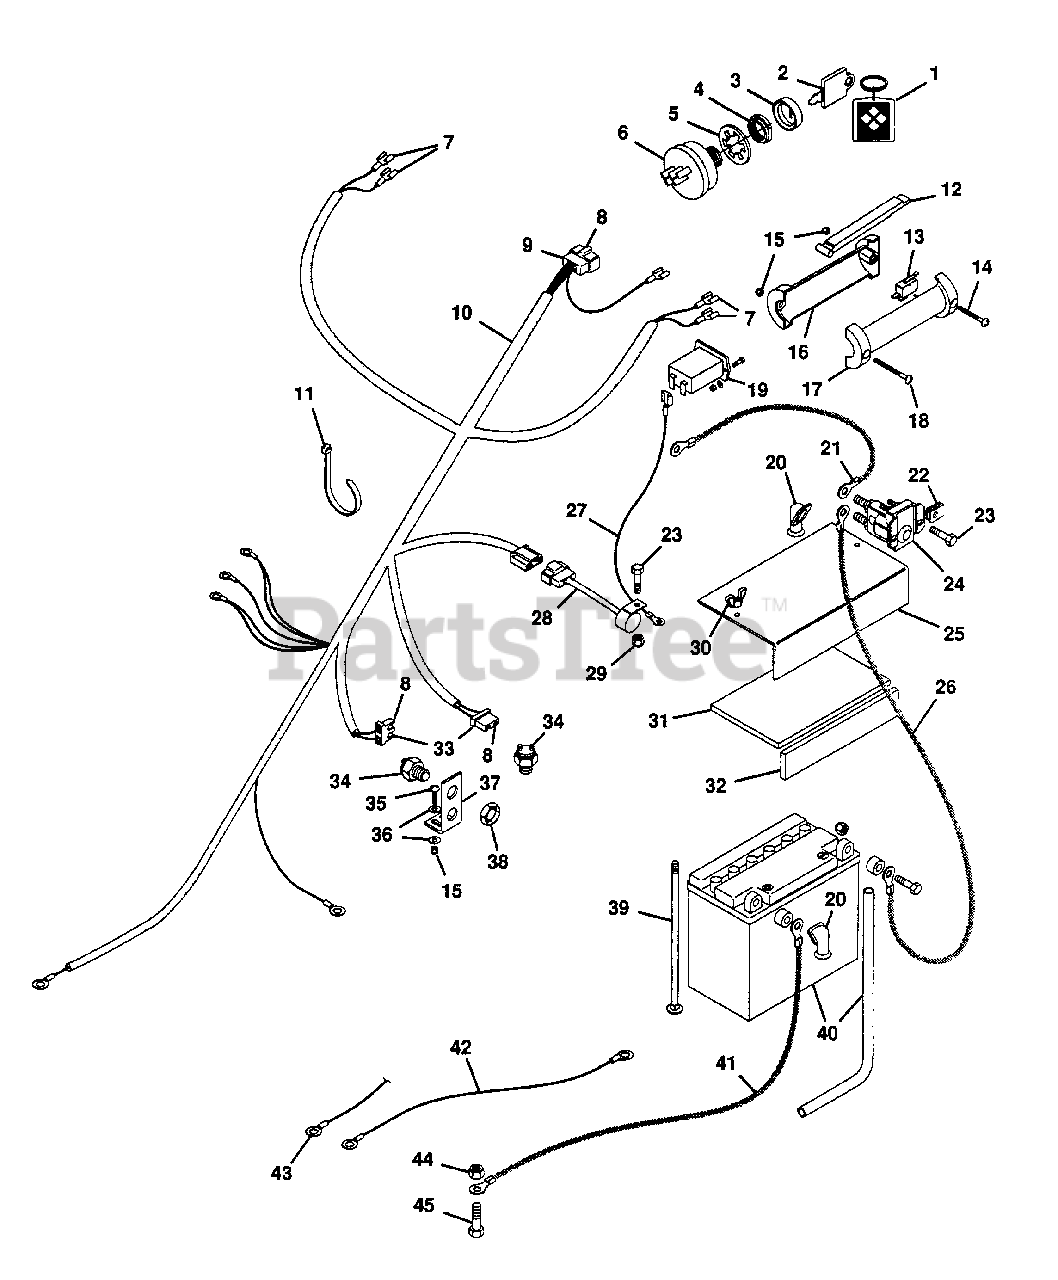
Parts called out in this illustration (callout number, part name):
1	CHAIN, KEY
2	KEY, IGNITION SWITCH
3	BOOT, FOR 9/16 SWITCH
4	NUT, 9/16-24 FOR SWITCH
5	WASHER, LOCK
6	SWITCH, IGNITION
7	TERMINAL, FEMALE
8	TERMINAL
9	CONNECTOR
10	HARNESS, WIRING
11	TIE, CABLE
12	LEVER
13	SWITCH
14	SCREW, MACHINE 10-24X.625 PHD
15	NUT, LOCK 10-24
16	HANDLE, R.H.
17	HANDLE, L.H.
18	SCREW, MACH. 10-24X1.50 PHDCR
19	HOURMETER
20	BOOT, BATTERY CABLE
21	CABLE, SOLENOID TO STARTER
22	NUT, SPEED 1/4-20
23	BOLT, HEX 1/4-20X.750
24	SWITCH, MAGNETIC
25	COVER, BATTERY
26	CABLE, BATTERY TO SOLENOID
27	WIRE, INSTRUMENT PANEL
28	MODULE, INTERLOCK
29	NUT, LOCK 1/4-20
30	NUT, WING 1/4-20
31	PAD, BATTERY
32	PAD, BATTERY
33	CONNECTOR, 2-WIRE SWITCH
34	SWITCH, NEUTRAL START
35	SCREW, MACHINE 10-24X.75 PHD
36	WASHER, FLAT .188X.438X.049
37	BRACKET, INTERLOCK SWITCH
38	NUT, STAMPED 9/16-18
39	BOLT, 1/4-20X7.00 RD HD SQ NK
40	BATTERY, 12 VOLT
41	CABLE, NEGATIVE BATTERY
42	WIRE, GROUND
43	TERMINAL, RING TONGUE
44	NUT, LOCK 5/16-18
45	BOLT, HEX 5/16-18X2.25
